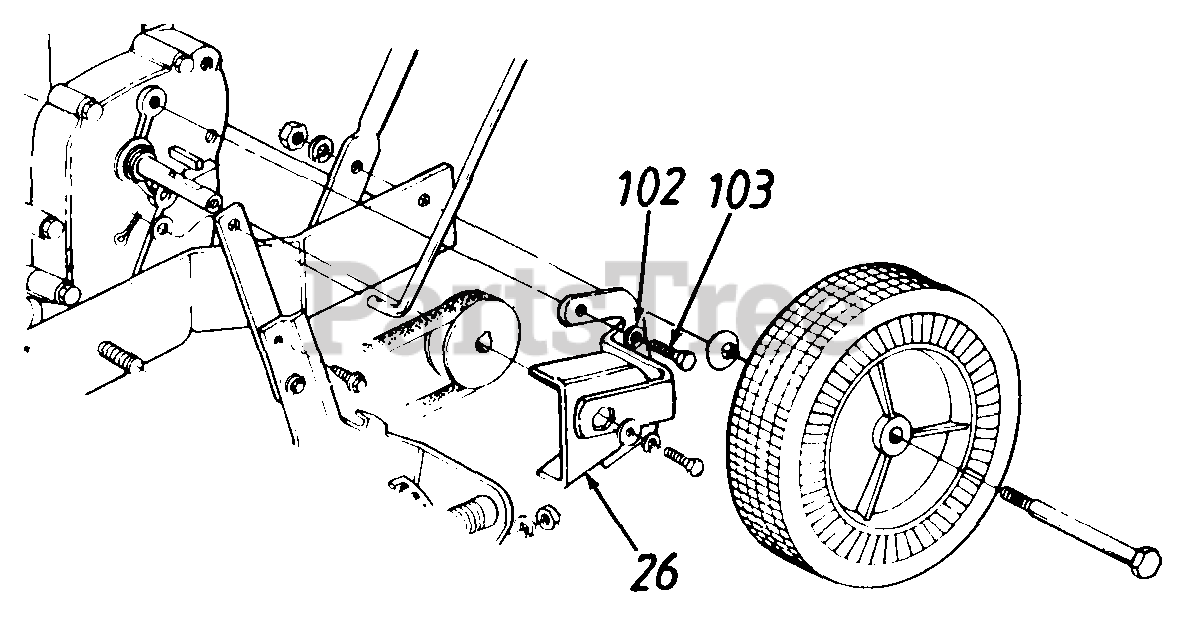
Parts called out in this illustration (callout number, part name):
26	Belt Guard Ass'y
102	L-Wash. 5/16 I.D.
103	Hex Screw 5/16-24 x .5"
